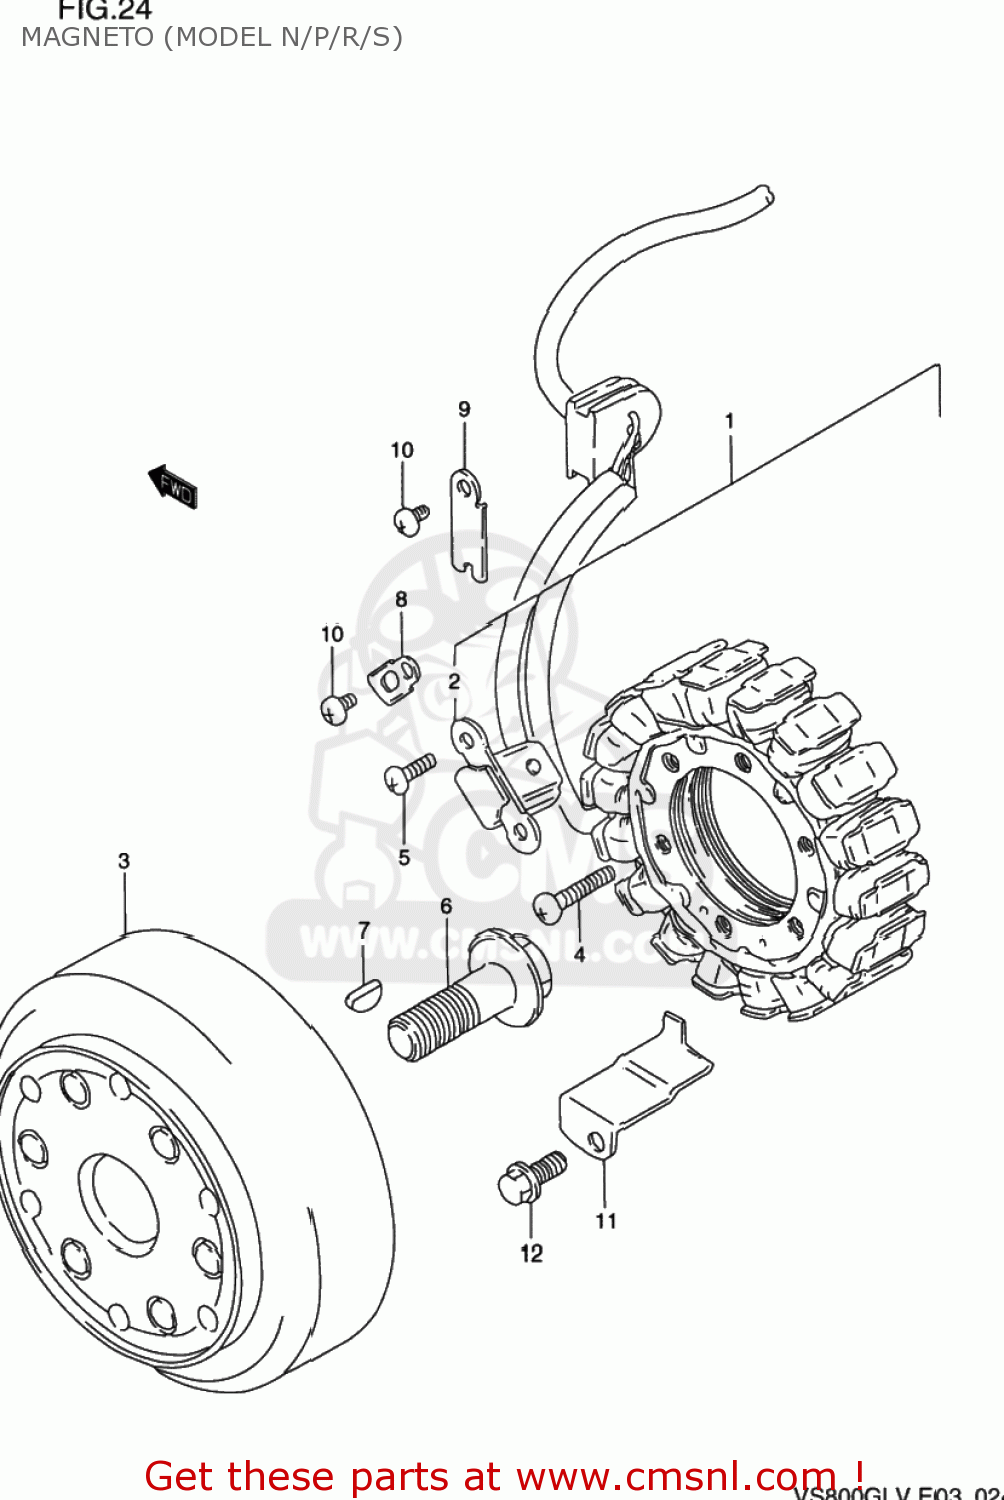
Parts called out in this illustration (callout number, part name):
1	STARTER ASSY
2	SENSOR & WIRE ASSY
3	ROTOR
4	BOLT
5	SCREW
6	BOLT(14X43)
7	KEY
8	CLAMP,GENERATOR LEAD WIRE
9	CLAMP NO.1,MAGNETO READ WIRE
10	SCREW
11	CLAMP,MAGNETO LEAD WIRE
12	BOLT
